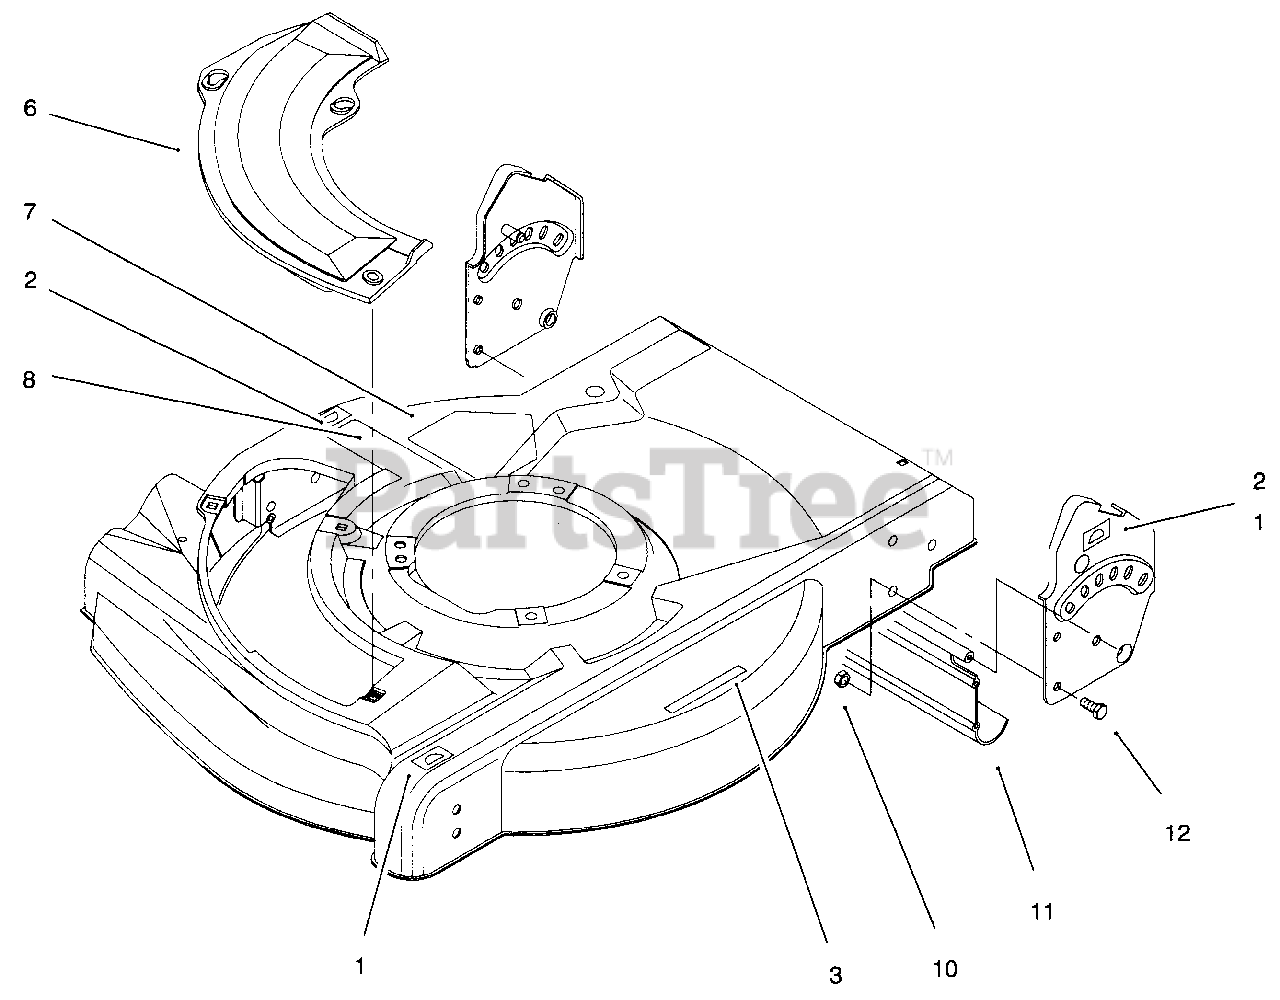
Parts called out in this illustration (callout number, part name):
1	Decal-H.O.C.
2	Decal-H.O.C.
3	Decal-Warning
5	Tie-Strap
6	Plate- Cover
7	Decal-Danger
8	Decal-Discharge
10	Nut-Lock
11	Shield-Trailing
12	Screw-Hex Hd. Cap
